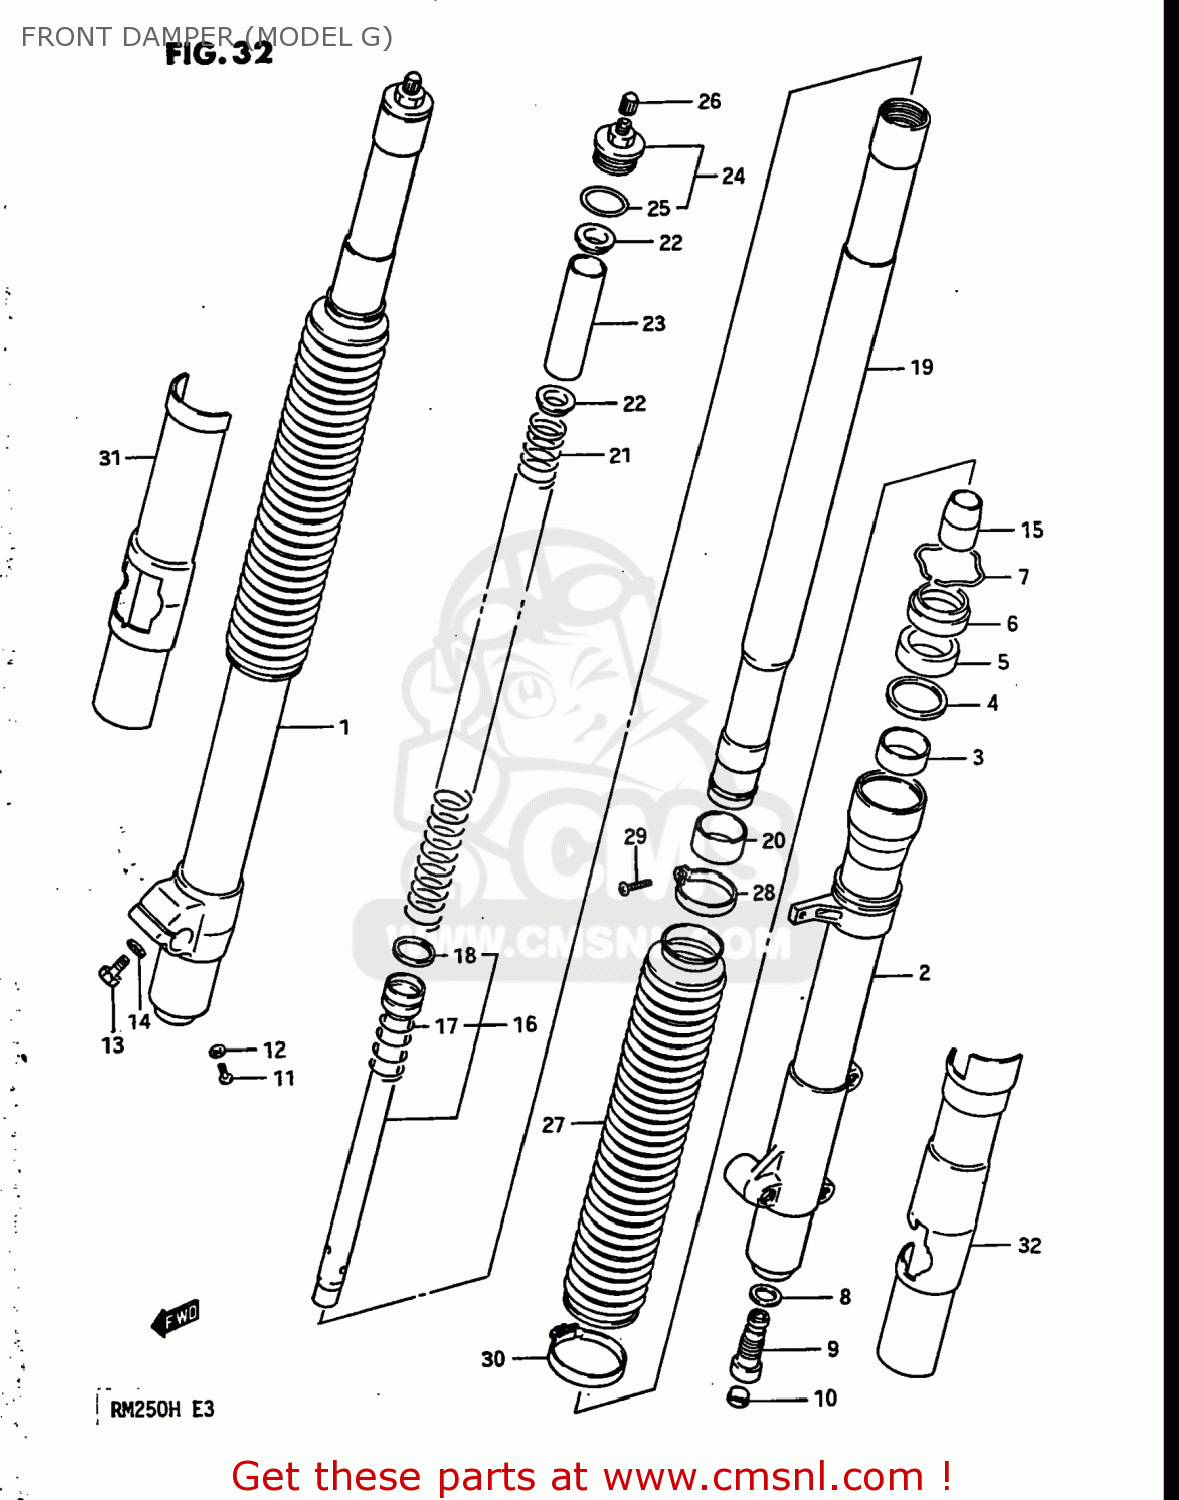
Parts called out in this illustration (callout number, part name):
1	TUBE,OUTER,RIGHT
2	TUBE,OUTER,LEFT
3	METAL,SLIDE
4	WASHER
5	SEAL,OIL
6	SEAL,DUST
7	RING,STOPPER
8	GASKET,FORK CYLINDER
9	VALVE,DF
10	CAP,FRONT FORK DF
11	SCREW 4X6
12	GASKET,DRAIN,PLUG (NAS)
13	BOLT
14	WASHER,LOCK,8.
15	PIECE,FRONT FORK OIL LOCK
16	CYLINDER,FRONT FORK
17	SPRING,REBOUND
18	RING,FRONT FORK PISTON
19	TUBE,FORK,INNER
20	PISTON
21	SPRING,FRONT FORK
22	GUIDE,FRONT FORK SPRING
23	SPACER,FRONT FORK SPRING
24	CAP,FORK INNER TUBE
25	O RING
26	CAP
27	BOOT
28	BAND,FRONT FORK COVER
29	SCREW 4X10
30	BAND,BOOT LWR
31	PROTECTOR,RIGHT
32	PROTECTOR,LEFT
